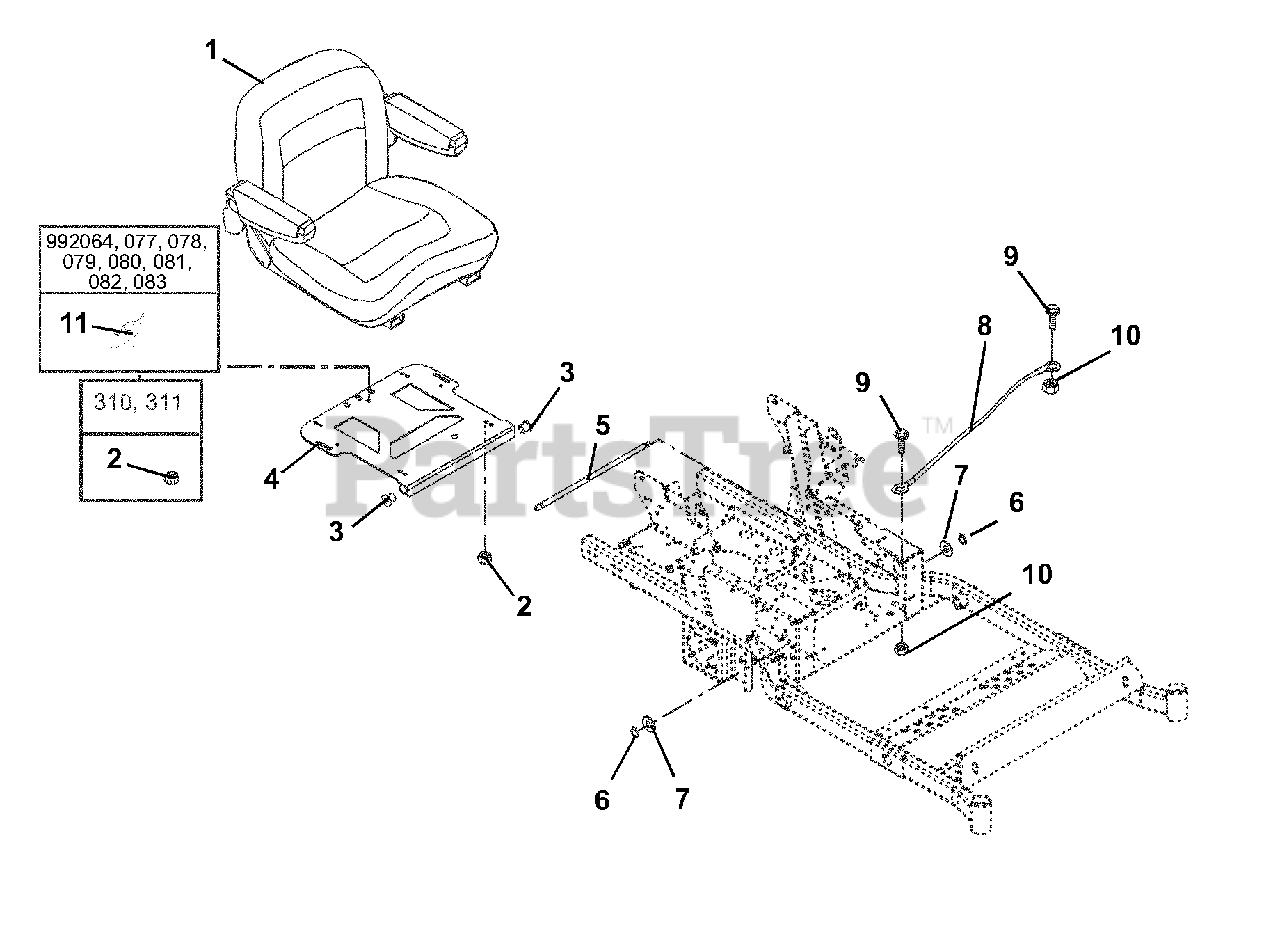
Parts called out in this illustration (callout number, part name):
2	Nut, Locking Top Flange .31-18 (064, 077, 078, 079, 080, 081, 082, 083)
2	Nut, Locking Top Flange .31-18 (310, 311)
3	Bushing, Flange .515 x .750 x .745 x 1.00
4	Seat Pivot Mount
5	Rod, Seat Frame Pivot
6	Ring, Retaining External .500 x .050
7	Washer, Thrust .531 x 1.00 x .063
8	Cable, Hood
9	Bolt, Hex .25-20 x .75 Grade 5
10	Nut, Locking Top Flange .25-20
11	Knob, Wing .312-18 (064, 077, 078, 079, 080, 081, 082, 083)
